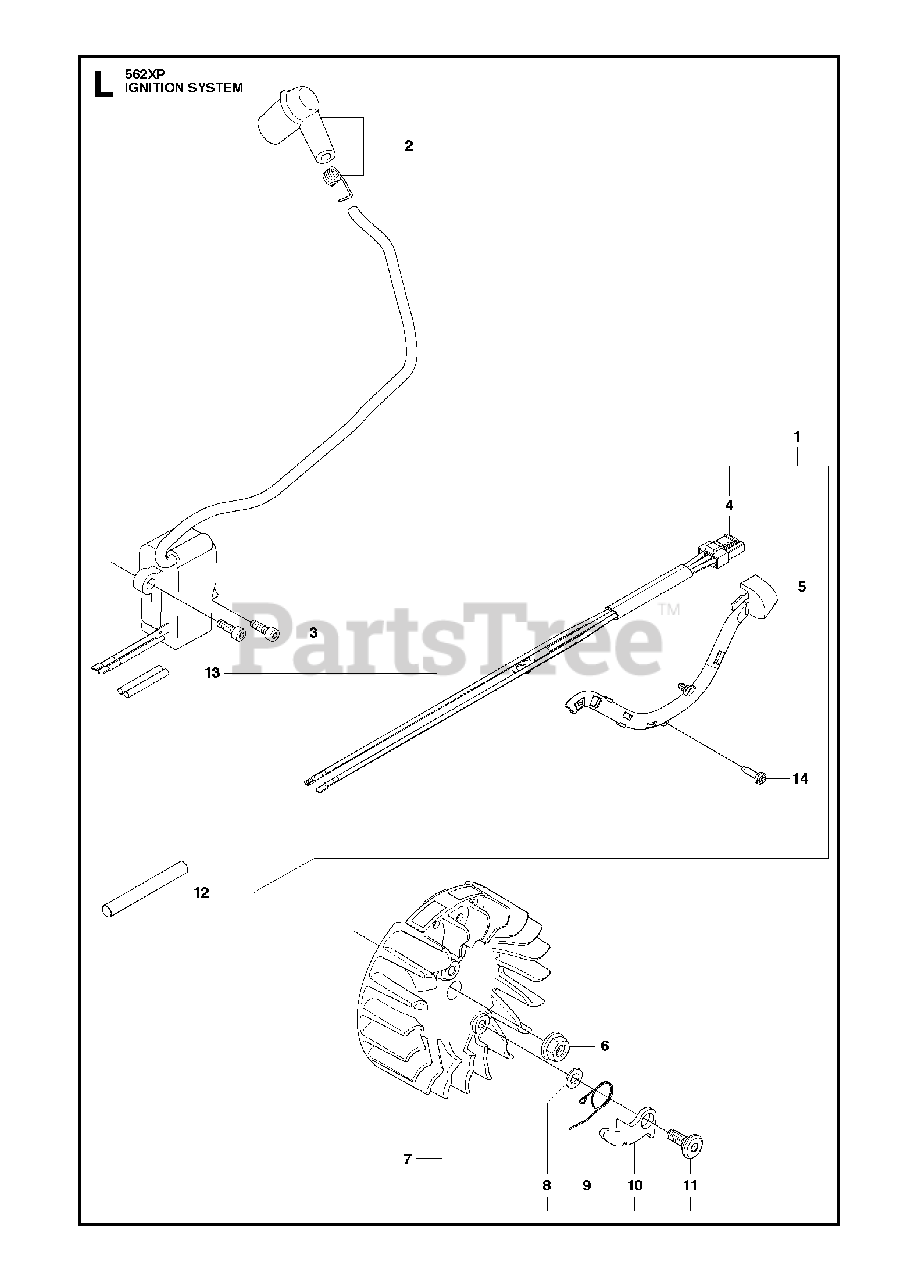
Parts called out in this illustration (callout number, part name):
1	IGNITION MODULE ASSY
2	SPARK PLUG CAP ASSY
4	WIRING ASSY
5	CABLE HOLDER
6	NUT W/ WASHER
7	FLYWHEEL ASSY
11	SCREW M5X14
12	CABLE COVER
13	SHRINK HOSE
